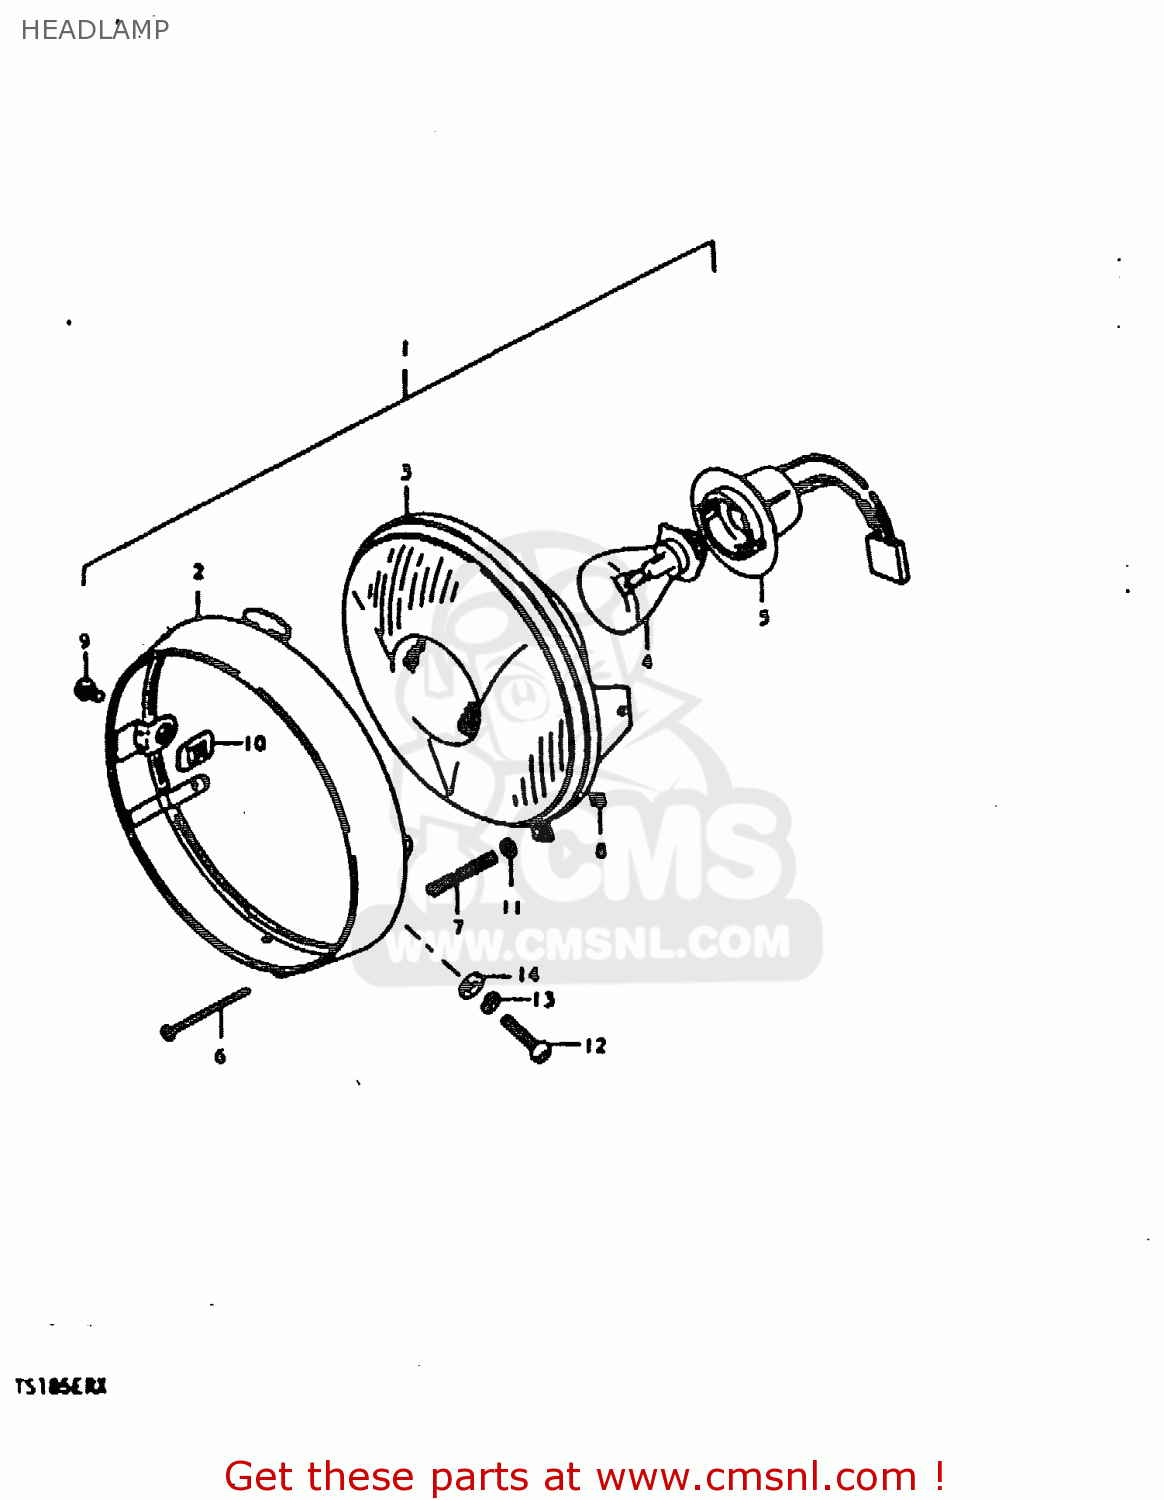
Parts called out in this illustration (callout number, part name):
1	HEADLAMP ASSY
2	RIM
3	LAMP UNIT
4	BULB(6V25/25W,STANLEY,A7007)
5	SOCKET,HEADLAMP
6	SCREW,HEADLAMP ADJUST
7	SPRING
8	NUT,HEADLAMP ADJUSTER
9	SCREW
10	NUT
11	WASHER
12	SCREW
13	LOCK WASHER
14	WASHER
